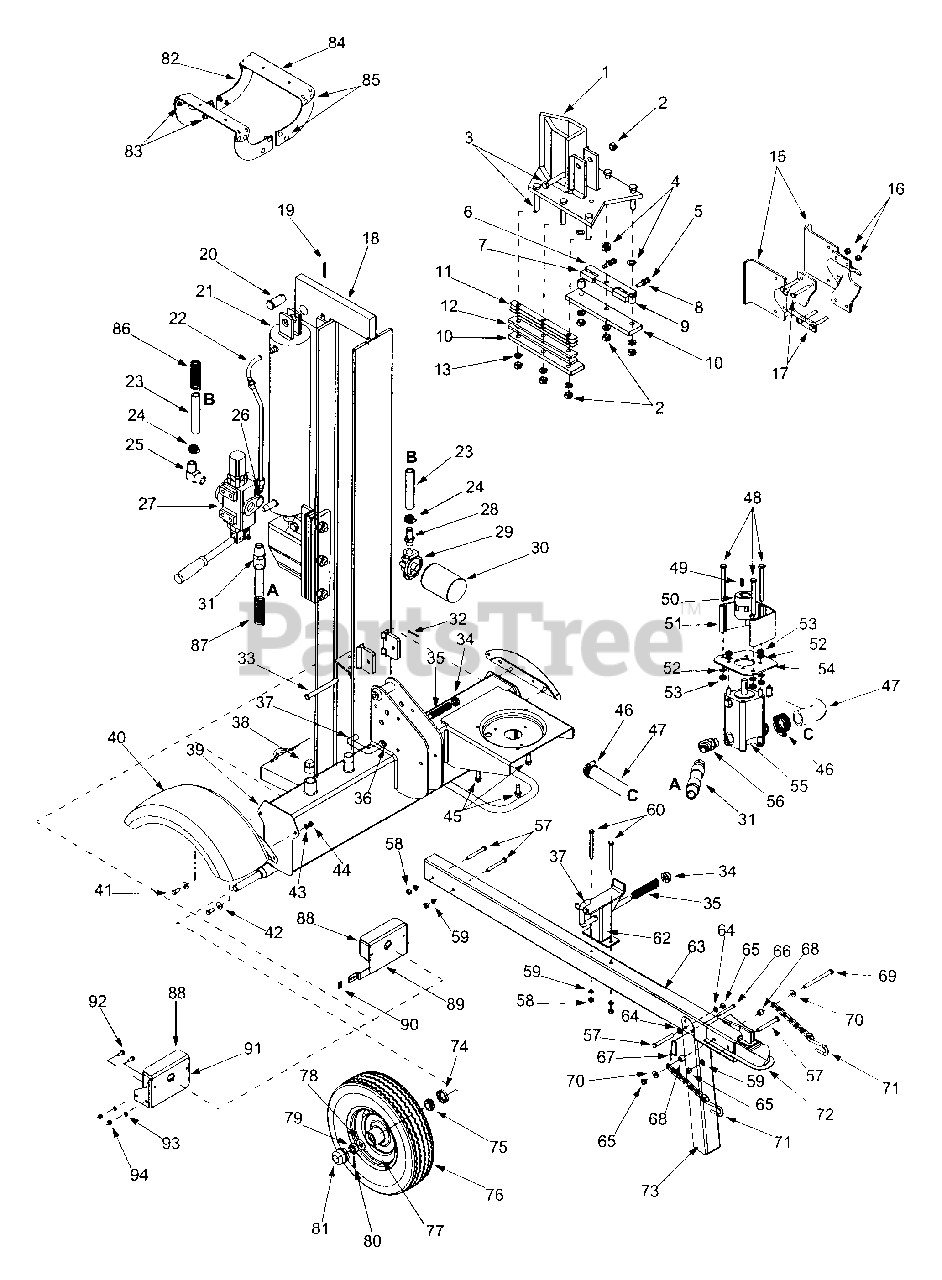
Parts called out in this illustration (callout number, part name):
1	Wedge Assembly
2	Lock Nut 1/2-20
3	Hex Cap Screw 1/2-20 x 2.75
4	Flat Washer .531 ID x 93 OD
5	Hex Cap Screw 3/8-24 x 1.5
7	Adjustable Gib
8	Hex Jam Nut 3/8-24
9	Spacer
13	Lock Washer 1/2
14	Lock Nut 1/2-20
17	Hex Cap Screw 3/8-16 x 2 5
23	Return Hose 3/4" ID x 44" Lg
24	Hose Clamp 5/8"
25	Return Elbow
26	90 Degree Solid Adapter
28	3/4" Hose Adapter
29	Filter Housing
30	Oil Filter
31	High Pressure Hydraulic Hose
33	Hinge Pin 1/2 x 4.8"
35	Compression Spring 4"
36	Flat Washer .635 ID x .93 OD
38	Pipe Plug
39	Frame Assembly 4.0 Gal
43	Lock Washer 5/16
44	Hex Nut 5/16-24
45	Hex Washer Screw 3/8-16 x 1.
47	Suction Hose
48	Hex Screw 5/16-24 x 3.25
49	Square Key 3/16" x .75
50	Flexible Coupling .750 x .500
50	Flexible Coupling .875 x .500
50	Flexible Coupling .875 x .437
51	Coupling Shield
52	Lock Washer 5/16" ID
53	Hex Nut 5/16-24
55	Gear Pump (11gpm)
55	Pump Kit
55	Gear Pump (9.5 gpm)
56	45 Degree Elbow
57	Hex Bolt 3/8-16 x 3"
58	Hex Nut 3/8-16
59	L-Washer 3/8"
60	Hex Bolt 3/8-16 x 4"
64	Flat Washer 3/8
65	Hex Lock Nut 3/8-16
66	Clevis Pin 5/16 x 2.5"
68	Spacer 3/8" ID x .625" OD
69	Hex Bolt 3/8-16 x 4"
70	Flat Washer 3/8" ID x .87" OD
71	Chain
72	Hitch Coupler
75	Bearing Cone
76	Wheel Assembly
77	Rim Assembly (Oyster Gray)
78	Flat Washer .76" ID x 1.5" OD
79	Slotted Nut 3/4-16
80	Cotter Pin 5/32" x 1-1/4"
85	Carriage Bolt 3/8-16 x 1.0
86	Hose Guard
87	Hose Guard
88	Taillight Assembly
93	Lock Washer 5/16
94	Hex Nut 5/16-24
